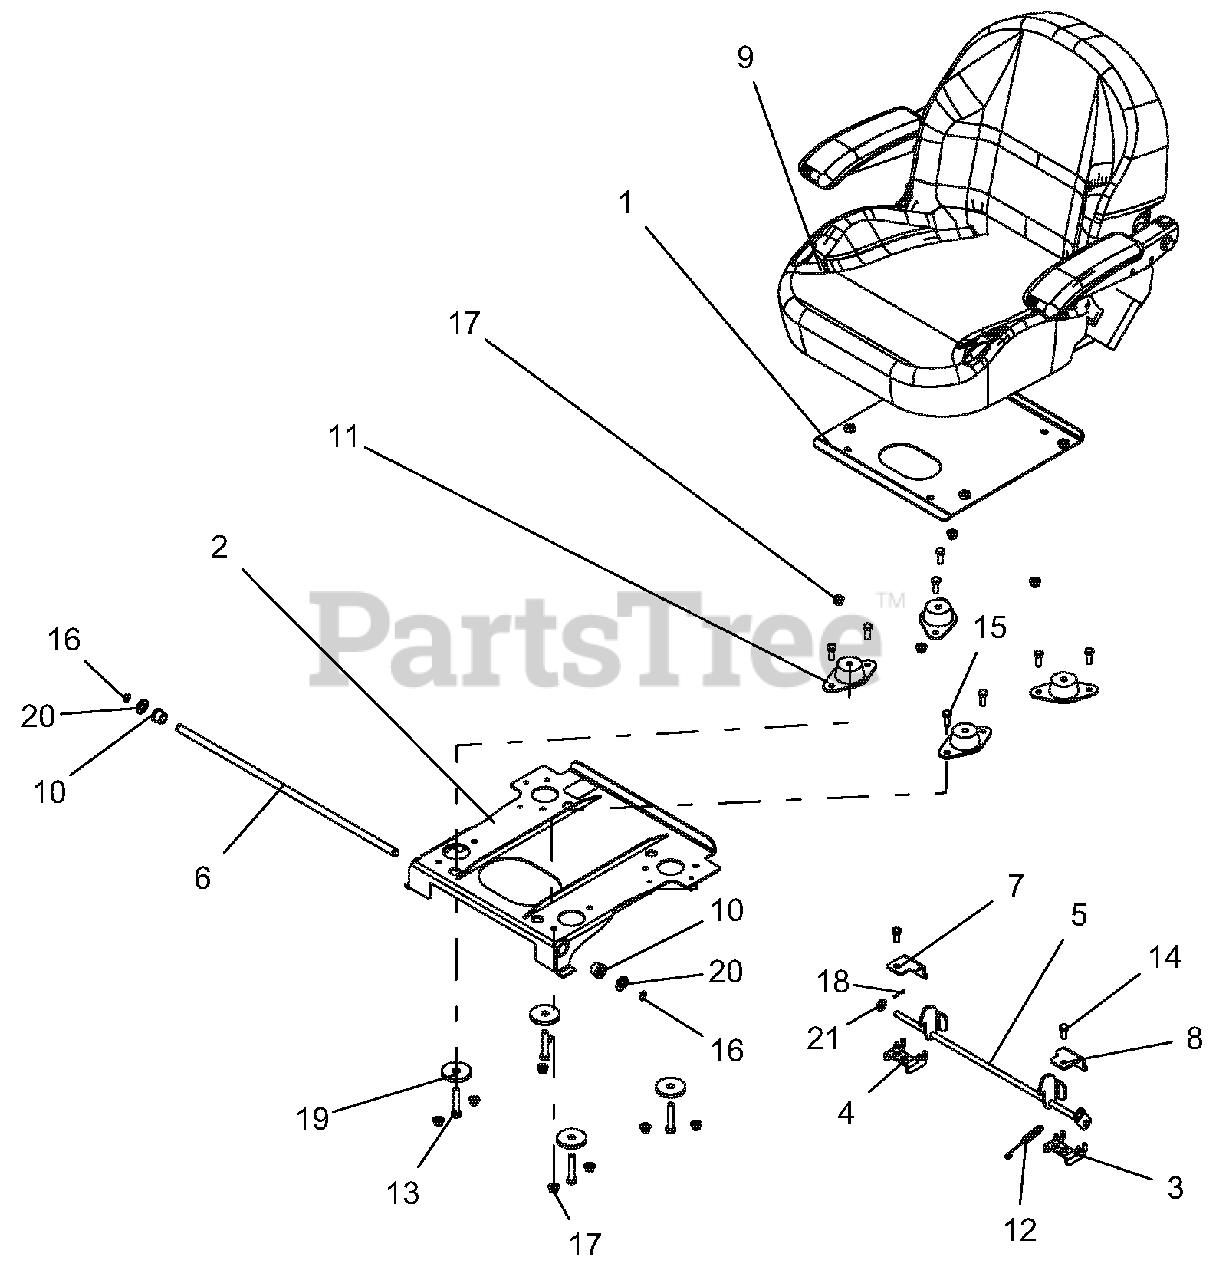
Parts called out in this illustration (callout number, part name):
1	WLDMT, SEAT MOUNTING PLATE-BLACK
2	WLDMT, PT ISOLATOR MTG PLATE-BLACK
3	WLDMT, PT/PT100 LH SEAT LATCH MOUNT-BLACK
4	WLDMT, PT/PT100 RH SEAT LATCH MOUNT-BLACK
5	WLDMT, PRO-TURN SEAT LATCH-BLACK
6	SHAFT, PT/PT100 SEAT PIVOT
7	MOUNT, PT/PT100 RH TOP SEAT LATCH-BLACK
8	MOUNT, PT/PT100 LH TOP SEAT LATCH-BLACK
9	SEAT, NON-SUSPENSION
10	BSHG, SHLDR EP .358-16X.30 HEX YZ
11	MOUNT, FAIL-SAFE COMPRESSION
12	SPRG, EXTENSION
13	BLT-HEX .38-16X2.00 GR5 YWZC
14	BLT-HEX .31-18X.75 GR5 YWZC
15	BLT-HEX .31-18X.875 GR5 YWZC
16	RG-RTNG-EXT .500x.050
17	NUT-LK-NYL-FLG .31-18 YWZC
18	@PIN-CTR .09X.75 EXTPRSQCT YWZ
19	WSHR-FL-STL .469X2.00X.25 YWZC
20	WSHR-FL-STL .531X1.000X.063 YWZC
21	WSHR-FL-STL.406X.812X.065 YWZ
